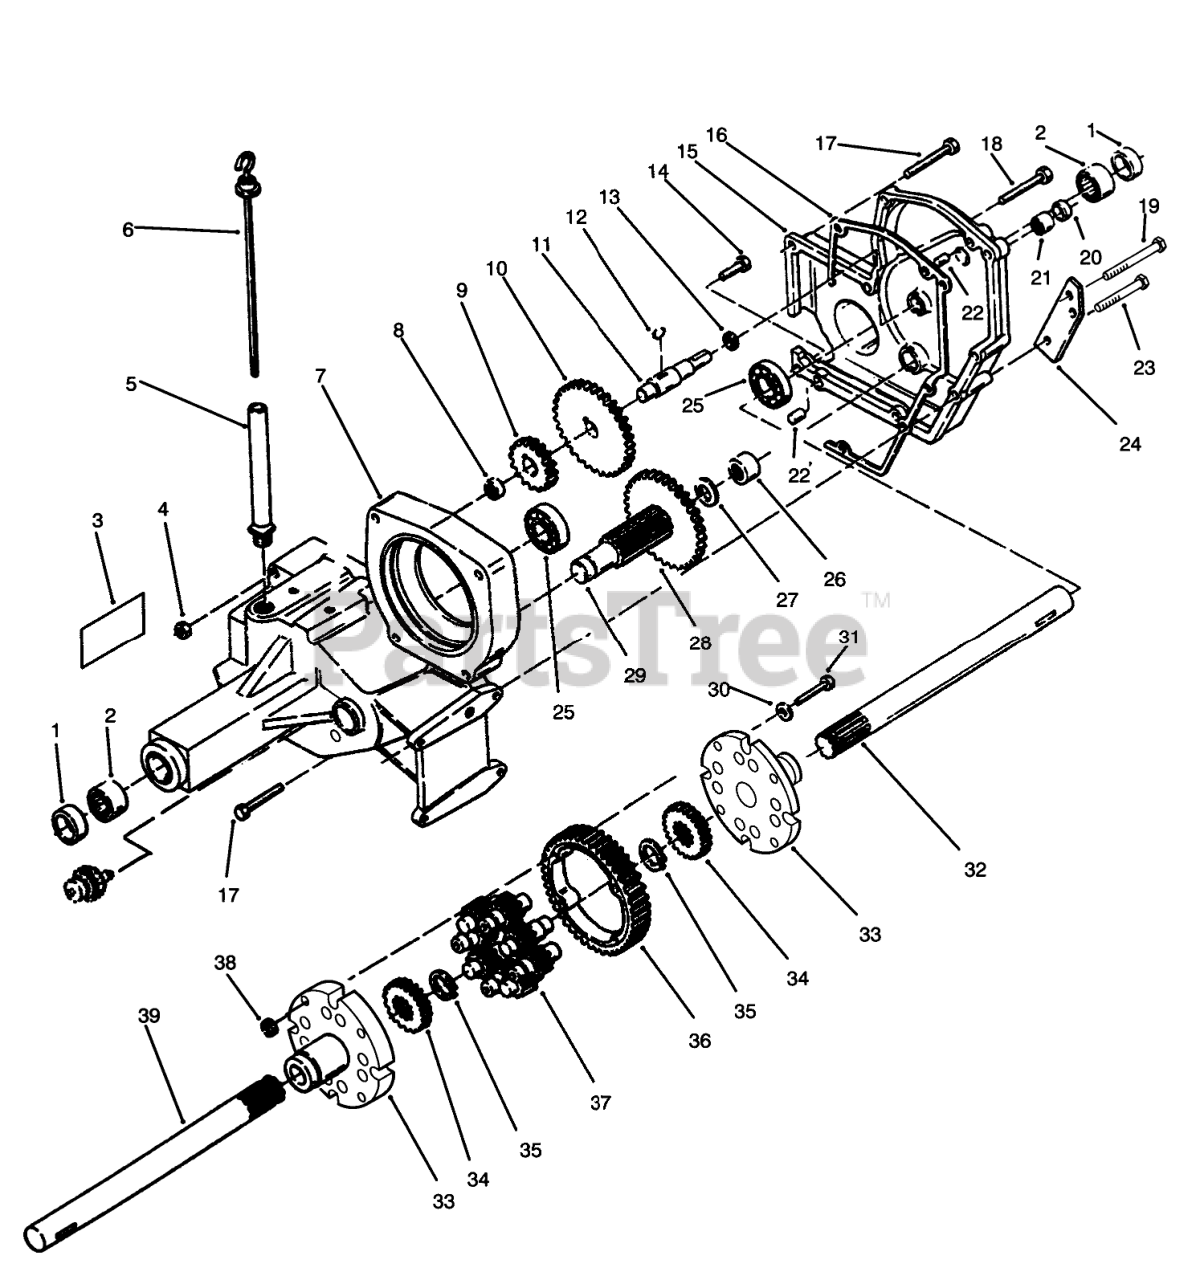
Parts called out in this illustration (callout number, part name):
1	SEAL-OIL
2	BEARING
3	DECAL - DANGER
4	NUT-LOCK, NI
5	NIPPLE-TRANS FILL
6	Dipstick
7	Case-Transaxle, RH (Incl. Ref. #3)
8	BEARING-NEEDLE
9	GEAR 20 TEETH
10	GEAR 46 TEETH
11	SHAFT GEAR
12	WOODRUFF KEY
13	Race Thrust
14	SCREW-HH
15	CASE TRANS LH
16	GASKET-TRANSMISSION
17	SCREW-HH
18	SCREW-HH
19	SCREW-HH
20	Seal
21	NEEDLE BEARING
22	PIN-LOCATING
23	SCREW-HH
24	BRACKET-BRAKEB
25	BEARING-BALL
26	BEARING-NEEDLE
27	WASHER-THRUST
28	GEAR 46T
29	PINION SHAFT
30	WASHER
31	BOLT-HEX
32	AXLE-REAR LH
33	END CAP-DIFFERENTIAL
34	GEAR-AXLE DIFFERENTIAL
35	RING-SNAP
36	GEAR-DIFFERENTIAL RING, 43T
37	GEAR-PINION, 11T
39	AXLE-REAR RH
